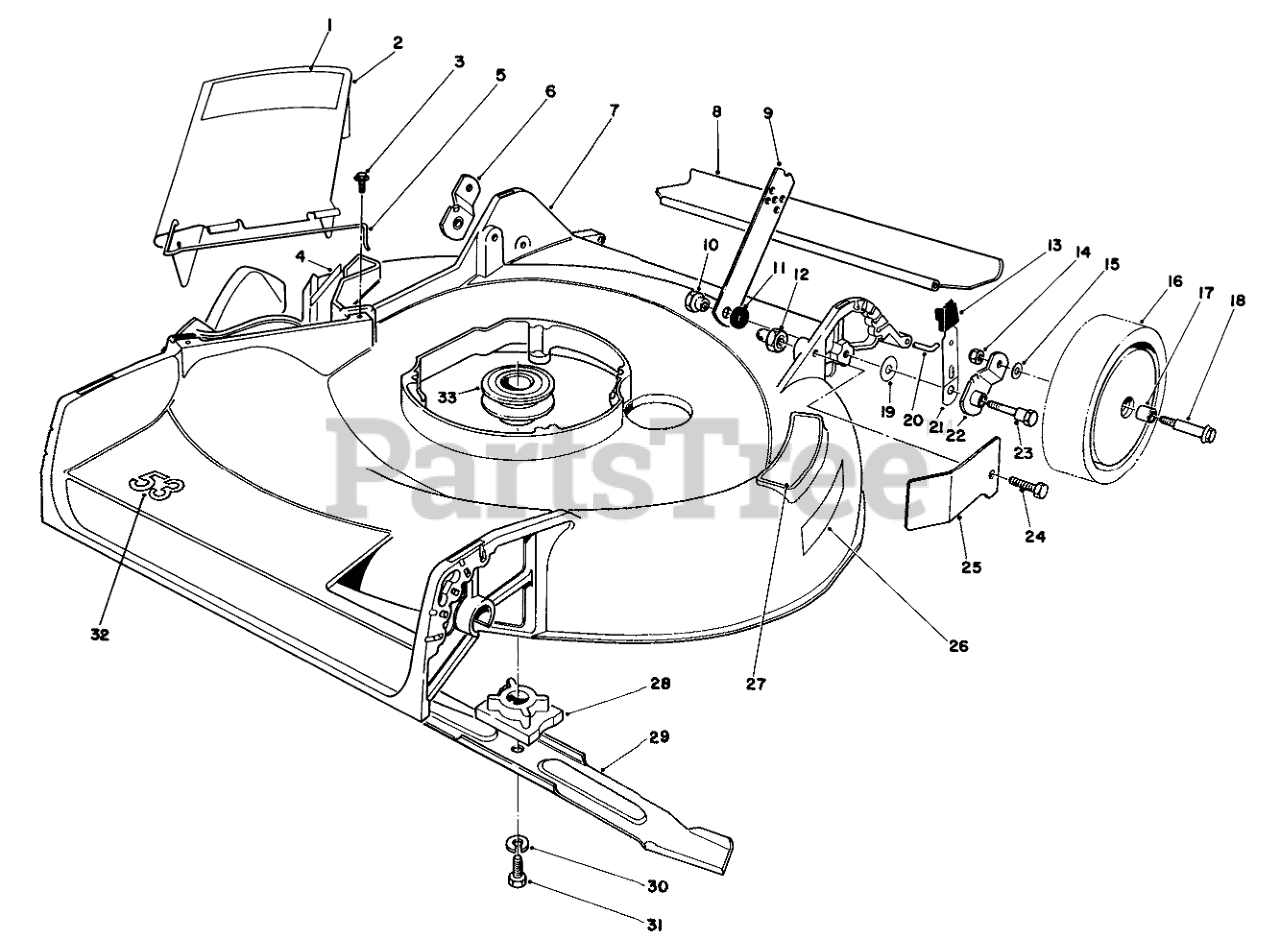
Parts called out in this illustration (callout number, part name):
1	DECAL - DANGER DEFL
2	Deflector Cover Assembly (Incl. Ref. #1)
3	SCREW-HWH
4	DANGER DECAL
5	SPRING HINGE
6	Pivot Arm
7	Housing (Incl. Ref. #26)
8	REAR SAFETY SHIELD 21
9	HANDLE LATCH
10	HANDLE PIVOT NUT
11	SPACER
12	HANDLE PIVOT NUT
13	KNOB-ARM
14	Nut
15	WASHER
16	Wheel & Tire Assembly (Incl. Ref. #17)
17	BUSHING
18	BOLT-WHEEL
19	WASHER-PIVOT
20	SHIELD ROD
21	SPRING ARM ASM
22	Pivot Arm
23	PIVOT SCREW
24	SCREW-HH
25	MUFFLER SHIELD
26	Decal Danger
27	DECAL - STEP PAD INT'L
28	BLADE RETAINER
29	Blade
30	WASHER-LOCK
31	SCREW-HH
32	DECAL - 53
33	Pulley
